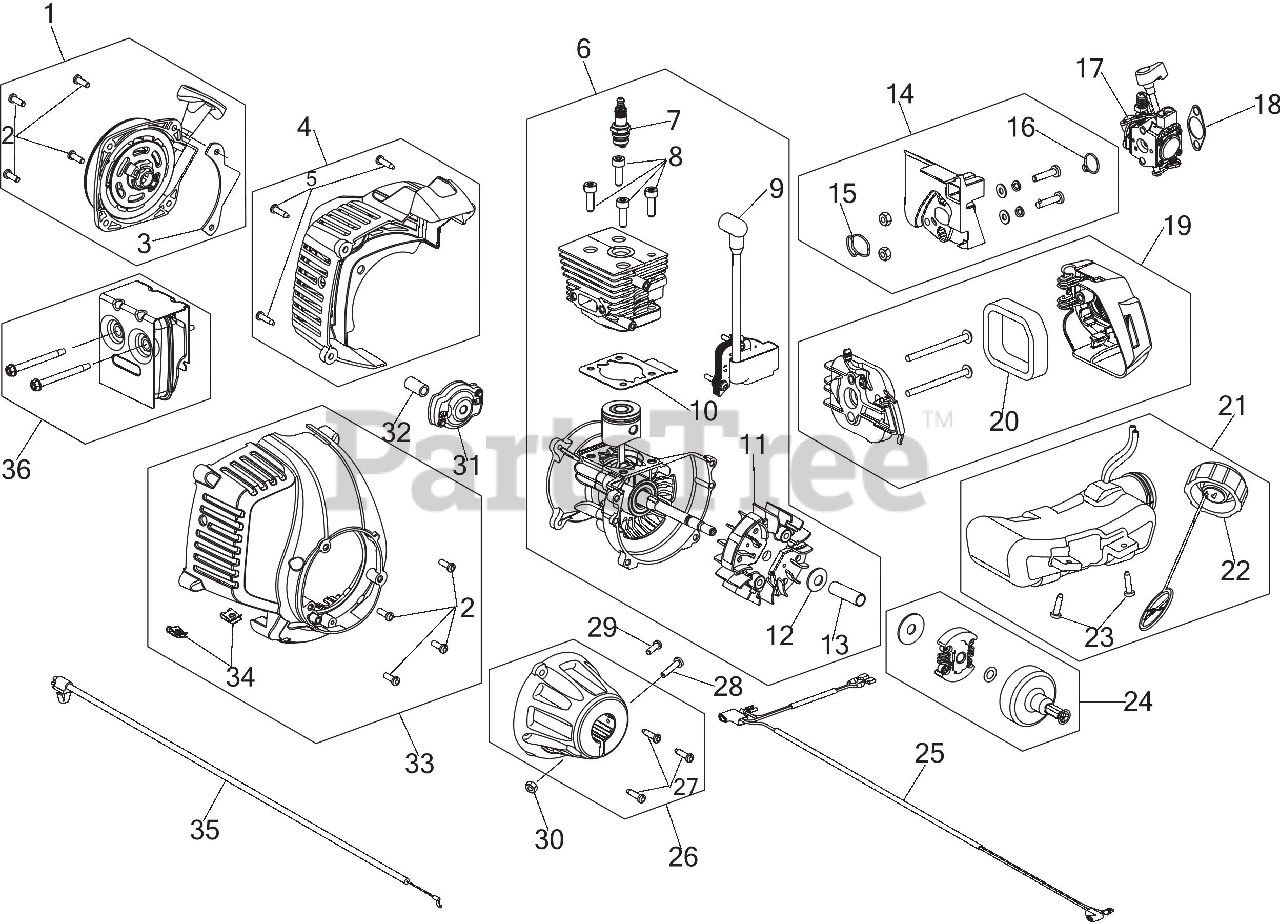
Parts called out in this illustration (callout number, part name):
1	STARTER ASSEMBLY RR
2	SCREW:10-32X.562:#8P
3	STARTER GUARD
4	ENGINE COVER ASSEMBLY RR
5	SCREW, #8-16X.750 PH
6	SHORTBLOCK 27CC
7	SPARK PLUG
8	SCREW 1/4X20
9	MODULE 27CC DIG
10	GASKET CYL
11	FLYWHEEL ASSEMBLY 27CC
12	BELL WASHER
13	SPACER
14	INTAKE ASSEMBLY
15	O-RING
16	O-RING
17	CARBURETOR
18	GASKET CARB
19	AIRCLEANER ASSEMBLY
20	AIR FILTER
21	FUEL TANK ASSEMBLY
22	FUEL CAP
23	SCREW:10-6 x .75
24	SMALL CLUTCH ASSEMBLY W/SMALL DRUM
25	LEAD WIRES
26	CLUTCH COVER ASSEMBLY
27	SCREW, #8-16X.750 PH
28	SCREW
29	SCREW, 8-32 x .312 P
30	HEX NUT
31	PAWL ASSEMBLY AC5
32	ELECTRIC START ADP
33	ENGINE COVER ASSEMBLY FRT
34	NUT, TINNERMAN U-T
35	THROTTLE CABLE
36	MUFFLER ASSEMBLY
